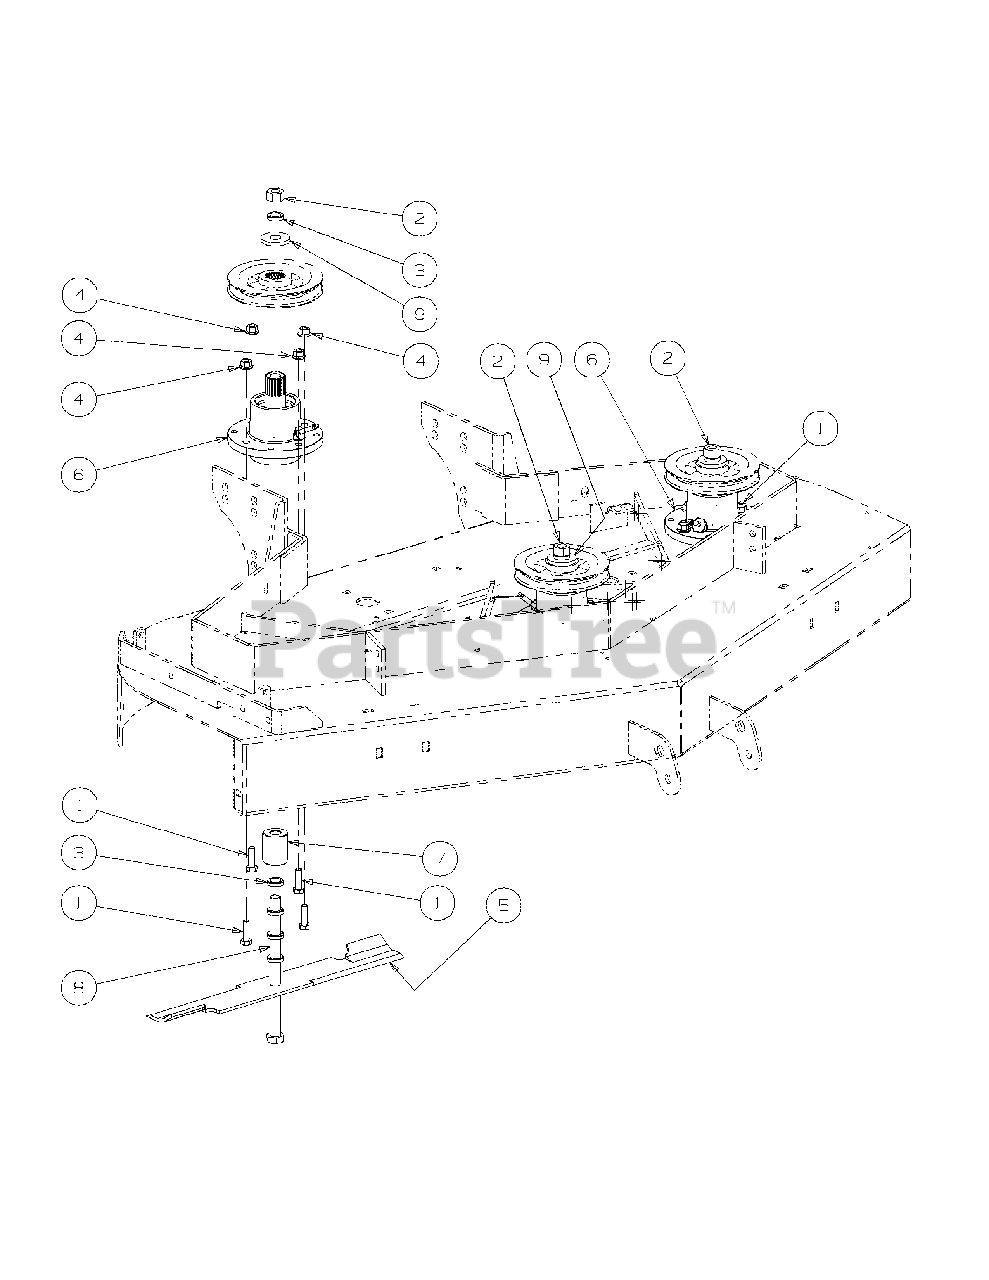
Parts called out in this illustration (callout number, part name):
1	Hex Cap Screw, 3/8-16 x 1-1/2
2	Hex Nut, 5/8-11
3	Blade Spacer, 5/8 ID, 1/4 Thick
4	Flange Lock Nut, 3/8-16
5	18" Rotary Blade
6	Spindle Assembly
7	Blade Spacer, .630 x 1.500 x 1.850
8	Hex Cap Screw, 5/8-11 x 9
9	Flat Washer, .656 ID x 1.75 OD
